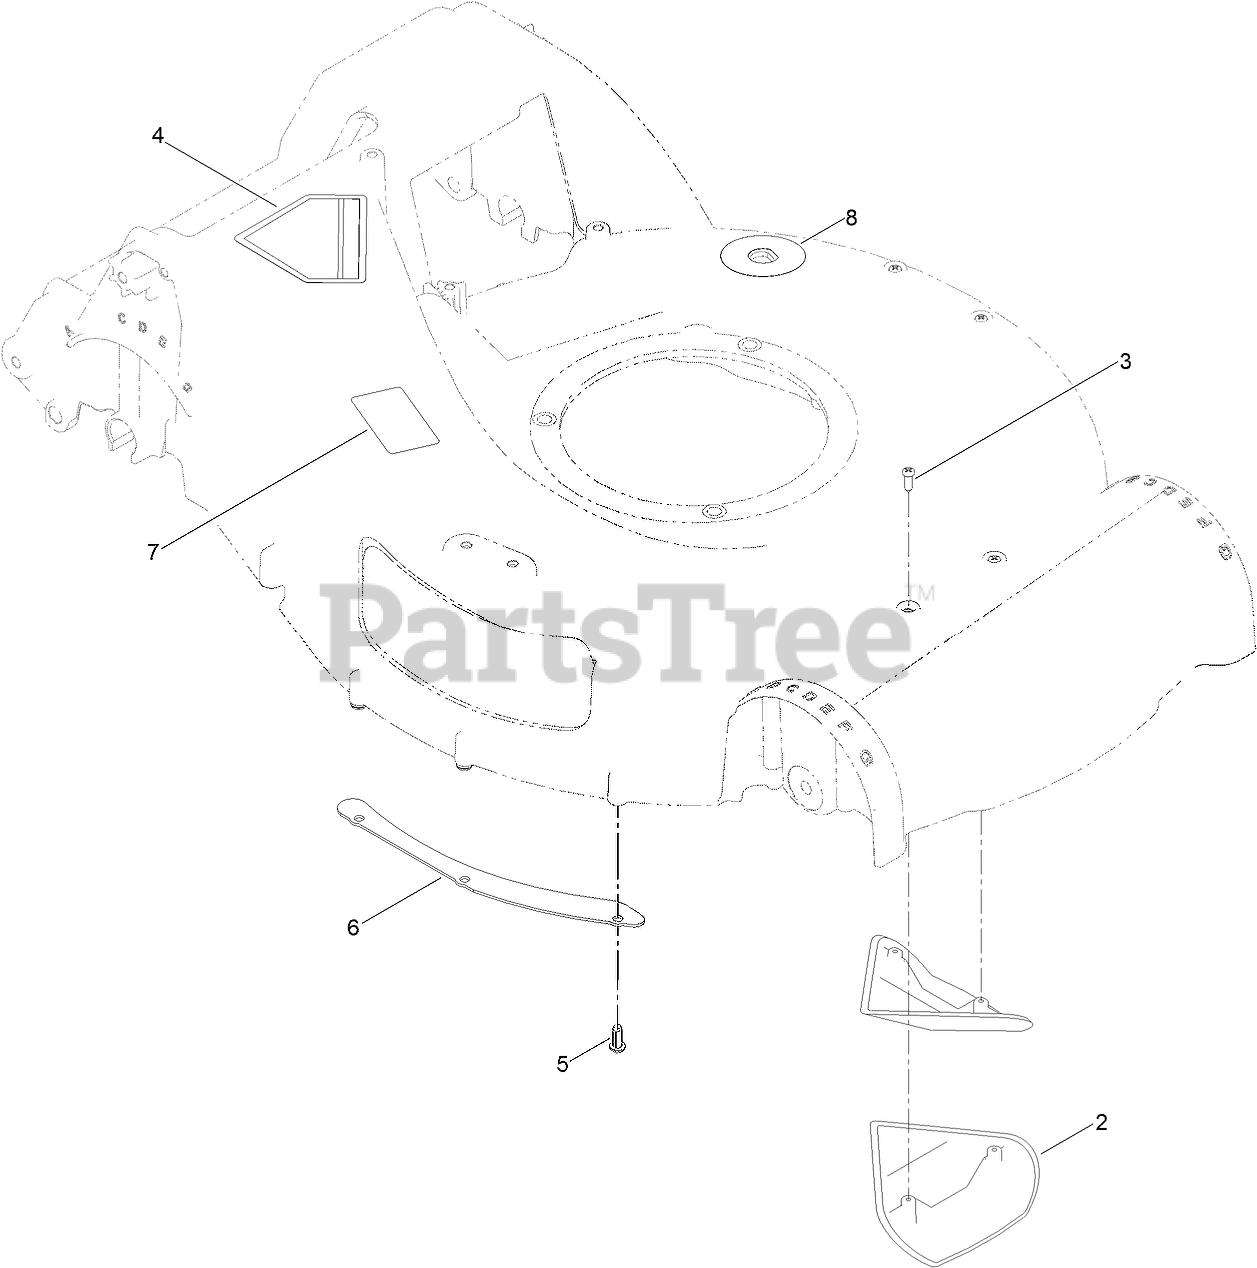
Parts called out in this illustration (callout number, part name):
2	KICKER-HOUSING
3	SCREW-PPH
4	DECAL-DANGER
5	SCREW
6	SHEET-LIP
7	DECAL-PLACEMENT, FOOT
8	DECAL-QUICK WASH
